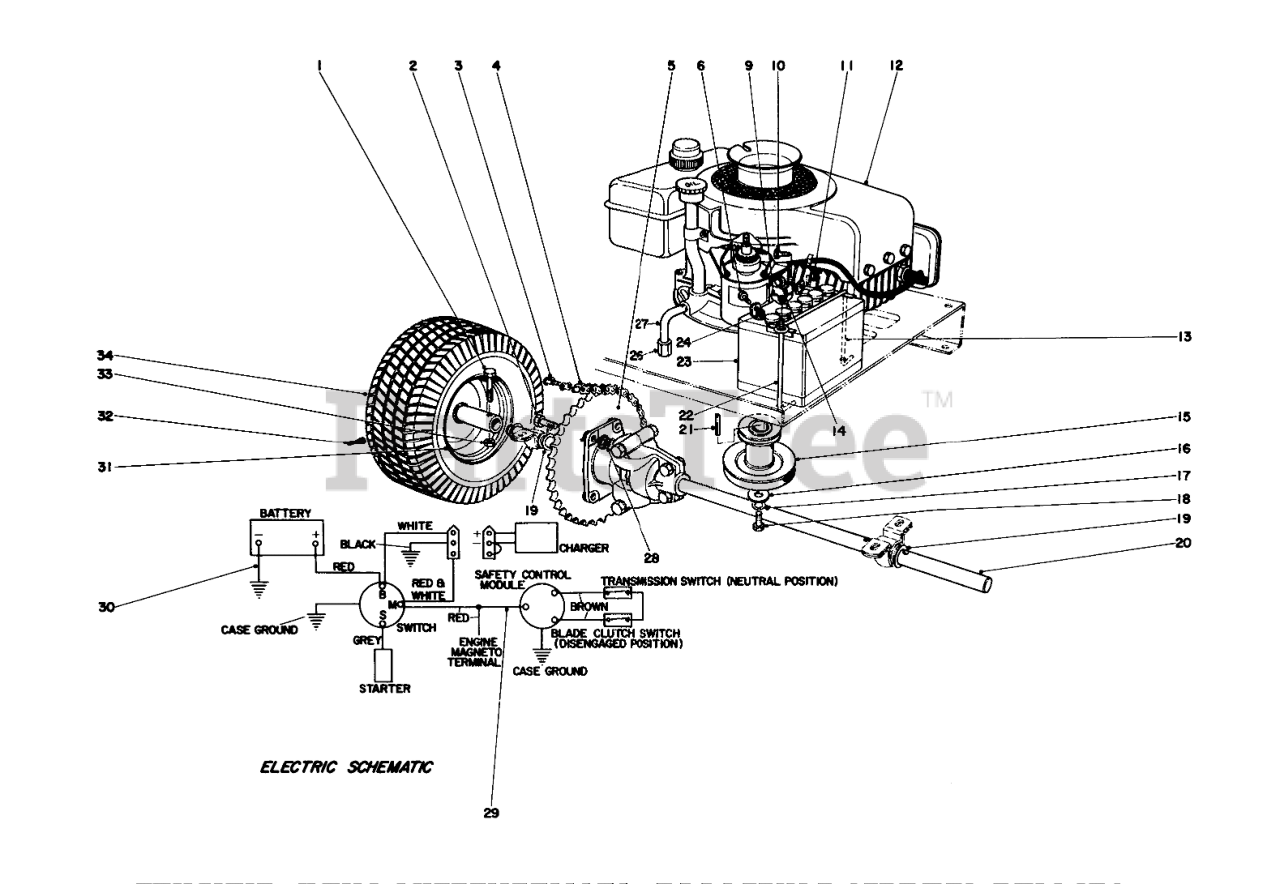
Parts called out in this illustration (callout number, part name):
1	SCREW-HH
2	SCREW-HH
3	LINK-CONNECTING
4	Chain
5	Sprocket
6	SCREW-HH
9	NUT-WING SPECL
10	SCREW-HH
11	NUT-HEX
12	Engine
13	Battery Clamp
14	SCREW
15	Pulley
16	Washer
17	WASHER-LOCK
18	SCREW-HH
19	WASHER
20	Differential
22	ROD-SUPPORT, BATTERY
23	Battery
24	NUT-HEX
26	Hex Cap
27	Elbow-Oil Drain
28	NUT-LOCK, CONE
29	Wiring Harness
30	ENG-GROUND WIRE ASM
32	STEM-VALVE
33	NUT-LOCK, CONE
34	Tire
